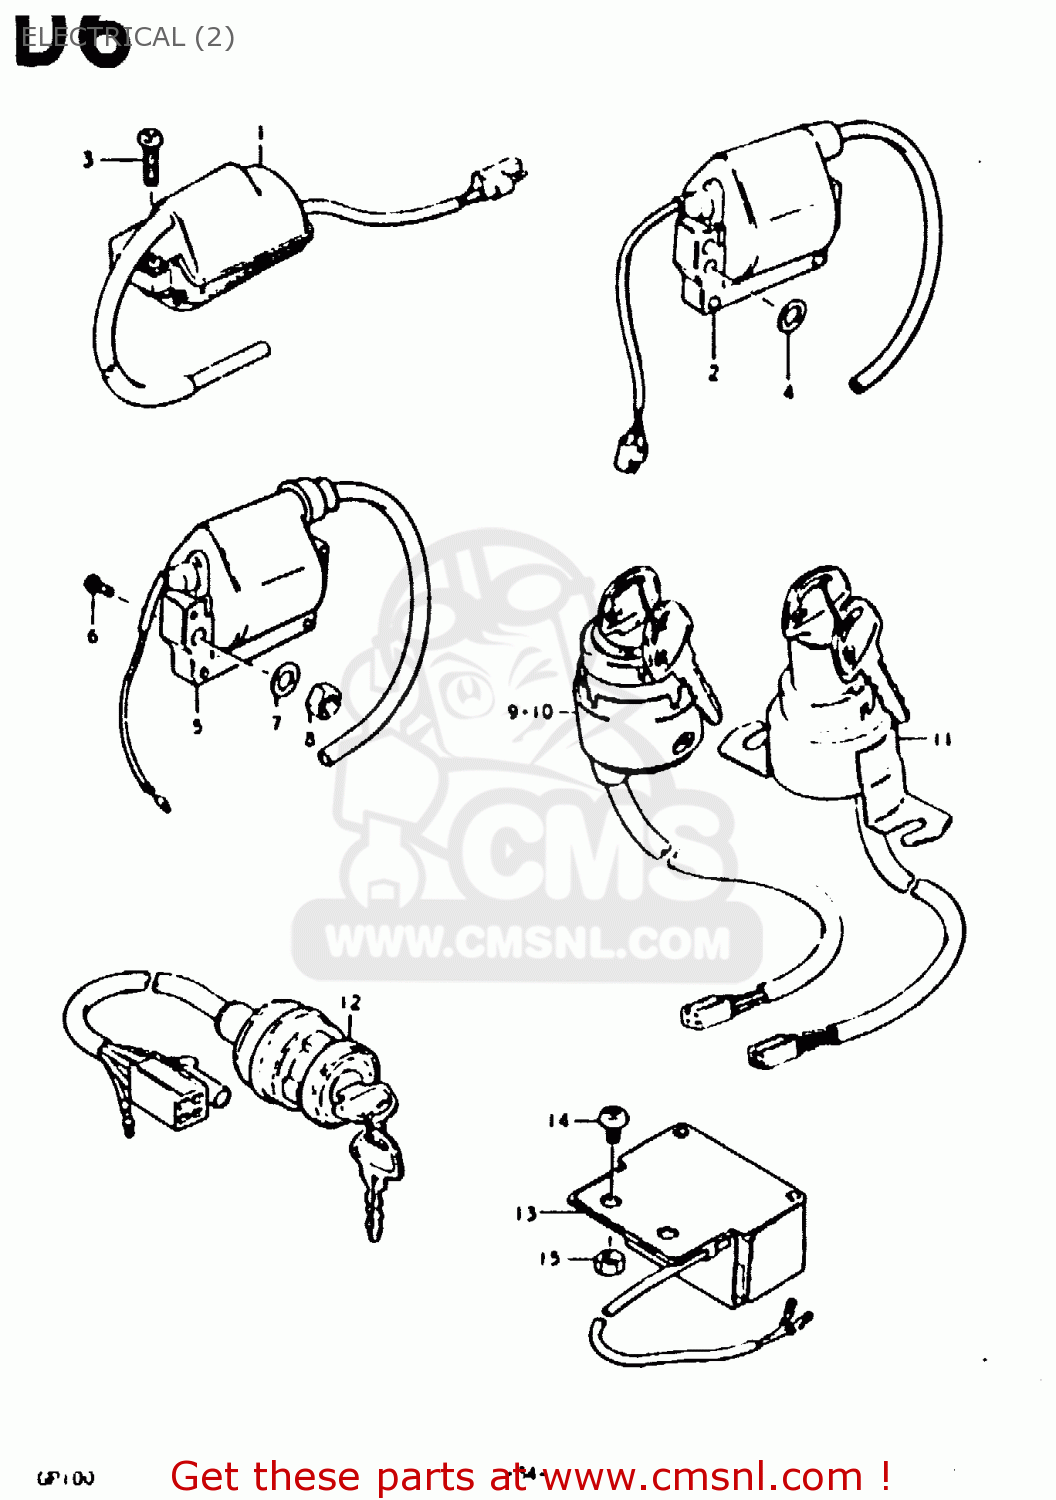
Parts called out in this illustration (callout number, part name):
5	COIL ASSEMBLY,IGNITION
6	SCREW 5X20
7	WASHER
8	NUT
12	SWITCH ASSY, IGNITION
13	RESISTOR ASSY
14	SCREW
15	NUT
